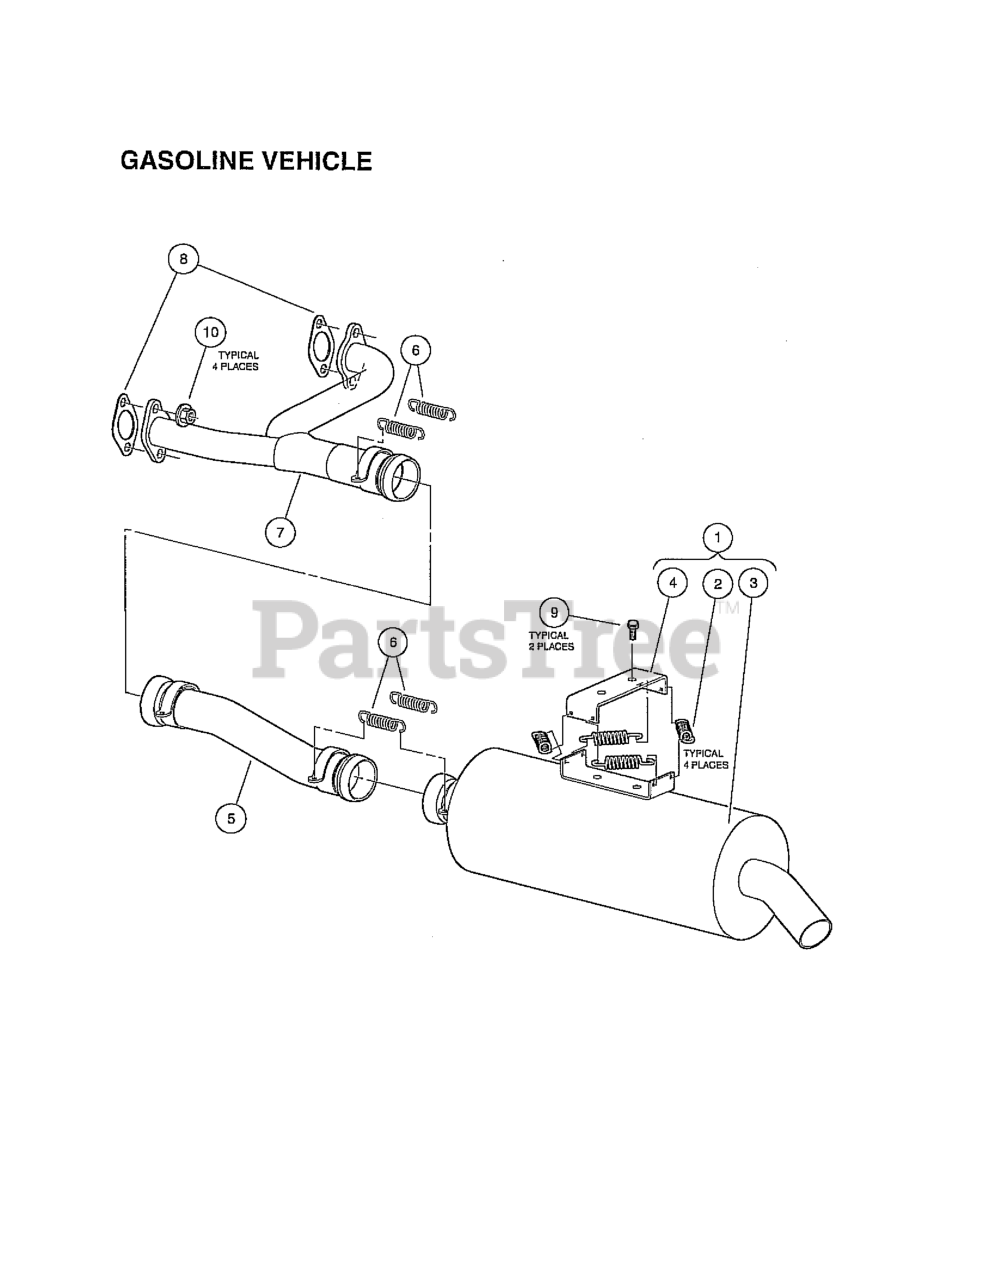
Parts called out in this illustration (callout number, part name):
1	ASM, MUFFLER
2	SPRING, EXHAUST
5	PIPE, EXHAUST INTERMEDIATE
6	SPRING, EXHAUST
7	HEADER, EXHAUST, GAS
8	GASKET, EXHAUST, GAS
9	BOLT FLG, M8X1.25X16 LOCTITE
10	NUT FLG, M8 X 1.25 SERRATED
